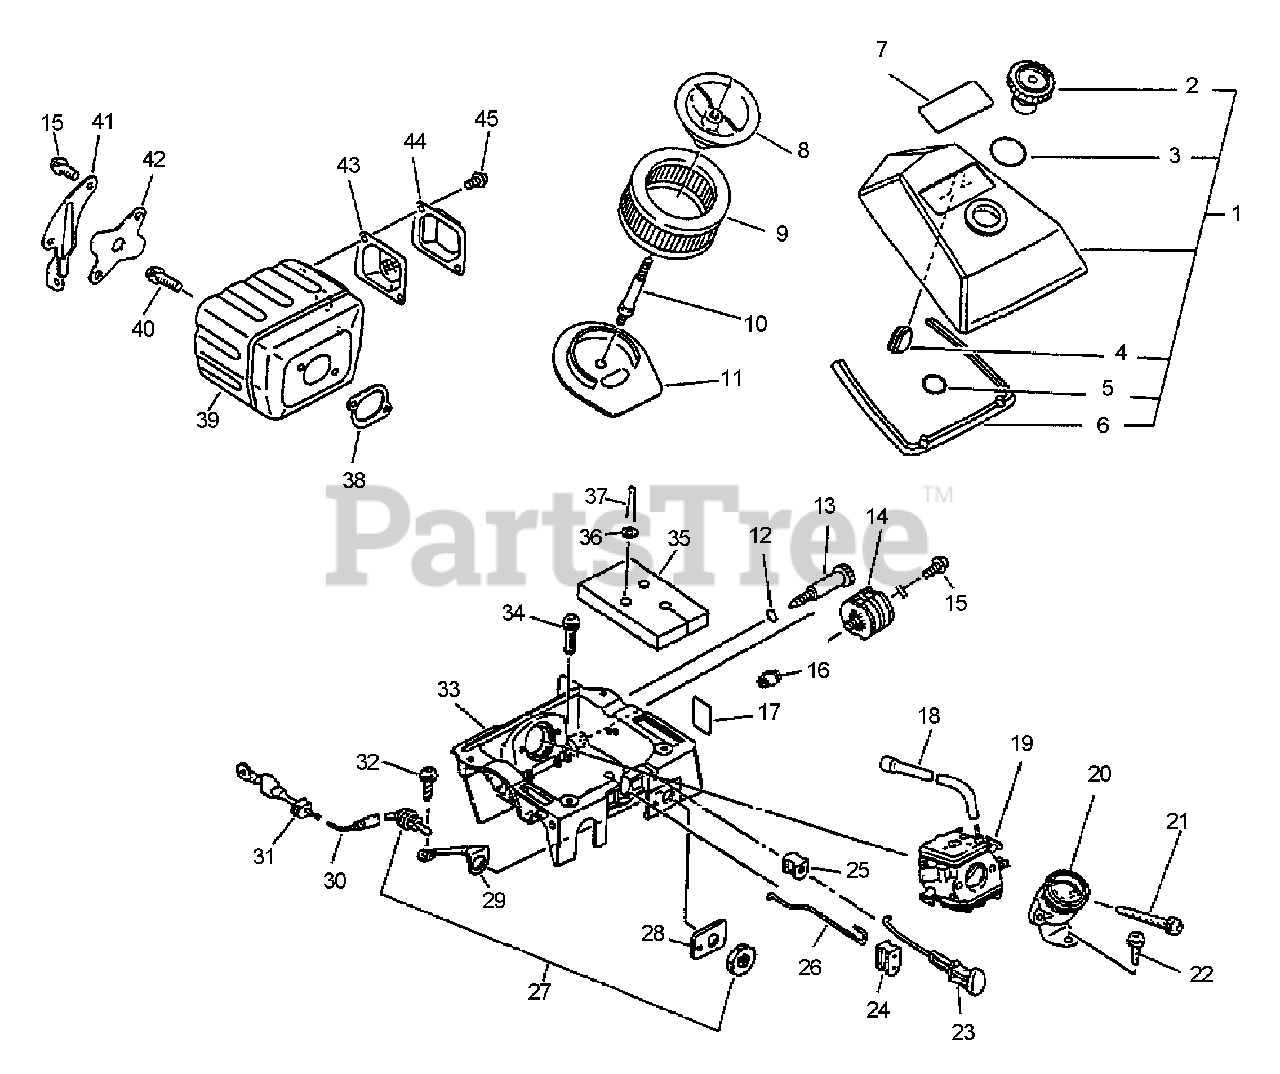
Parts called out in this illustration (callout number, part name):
1	AIR FILTER COVER ASSY
2	THUMBNUT
3	O-RING - 21
5	O-RING - 11
6	SEAL
7	LABEL - MODEL
8	COVER, AIR FILTER
9	AIR CLEANER ASSY
10	STUD
11	BRACKET, AIR CLEANER
12	O-RING - 7
13	SCREW, IDLE ADJUST
15	SCREW - 5X14
17	LABEL - IDLE
18	PIPE - IMPULSE
19	CARBURETOR HDA-76
19	CARBURETOR HDA-151A
20	ADAPTOR, INTAKE
21	SCREW - 5X55
22	SCREW - 5X14
23	ROD, CHOKE
24	GUIDE, THROTTLE ROD
25	GROMMET
26	ROD, THROTTLE
27	IGNITION SWITCH ASSY
28	LABEL - STOP
29	TERMINAL - GROUND
30	LEAD - GROUND
32	SCREW - 4X10
33	CASE, CARBURETOR
34	SCREW - 5X20
37	PIN, SPLIT - 3X18
38	GASKET, EXHAUST
39	MUFFLER
40	SCREW - 5X20
41	BRACKET, MUFFLER
42	COVER, MUFFLER
43	SCREEN, SPARK ARRESTOR
44	GUIDE, EXHAUST
45	SCREW - 4X10
